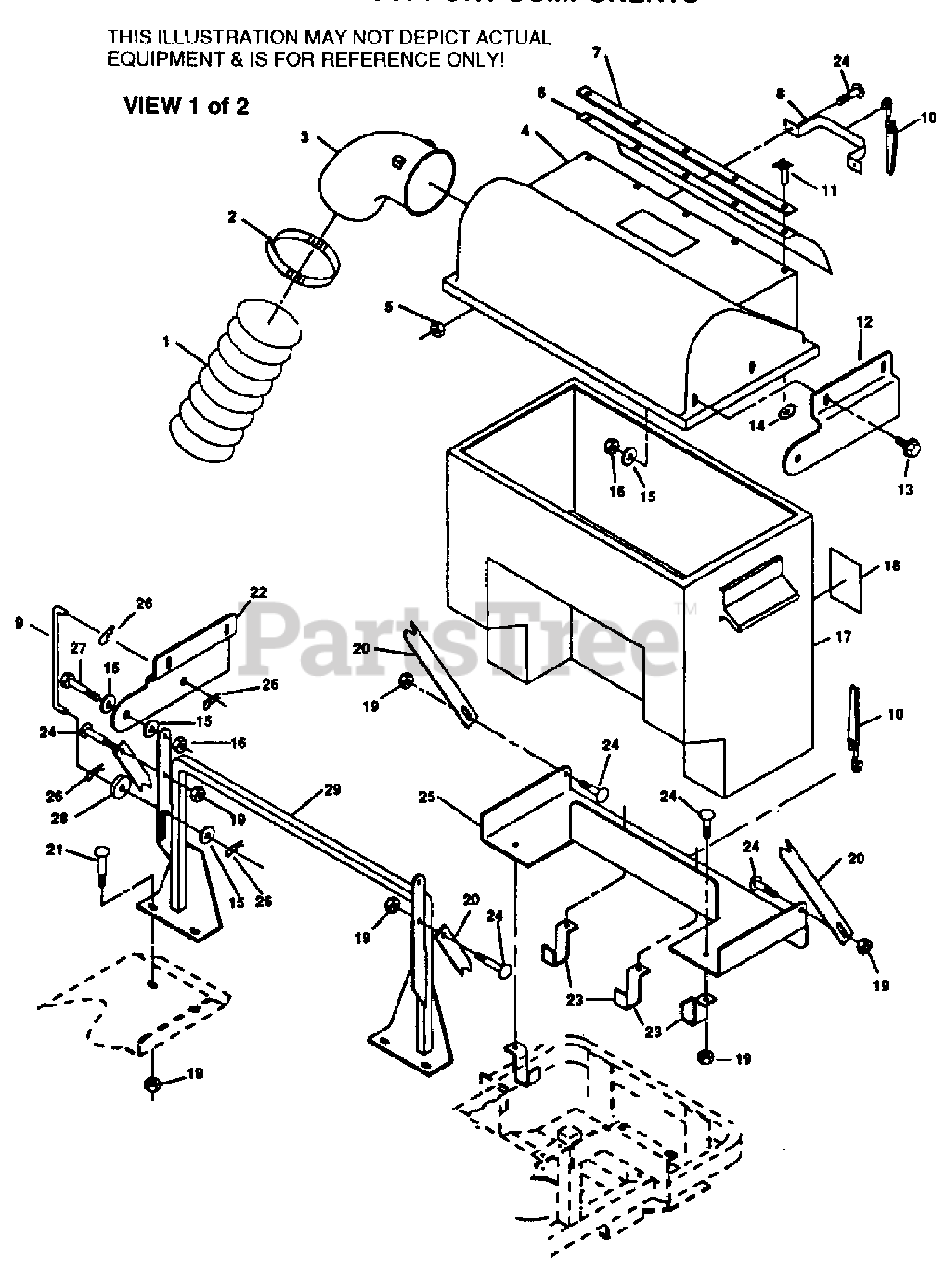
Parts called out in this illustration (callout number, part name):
1	HOSE 6" X 48"
2	CLAMP, HOSE
3	ELBOW, GRASS CATCHER
4	COVER ASSEMBLY, GRASS CATCHER,(INCL. 6, 7
5	NUT, 5/16" ELASTIC STOP
6	DEFLECTOR, GRASS CATCHER
7	BACKING PLATE, DEFLECTOR
8	HANDLE
9	ROD, COVER SUPPORT
10	STRAP, RUBBER
12	HINGE, LH
13	CAPSCREW, 3/8-16 X 1" SERR. FLANGE
14	WASHER, POP RIVET
15	FLAT WASHER .3/8"(.391 X .938 X .105)
16	NUT, 3/8-16 ELASTIC STOP
17	HOPPER, GRASS CATCHER W/DECAL
18	DECAL, HOPPER
19	NUT, 5/16-18 SERR FLANGE HEX HD.
20	BRACE
22	HINGE, RH
23	CLAMP, TRAY
25	TRAY
26	HAIR PIN, .080 DIA X 1.19
28	FLAT WASHER, 3/8"
29	SUPPORT FRAME WELDMENT
